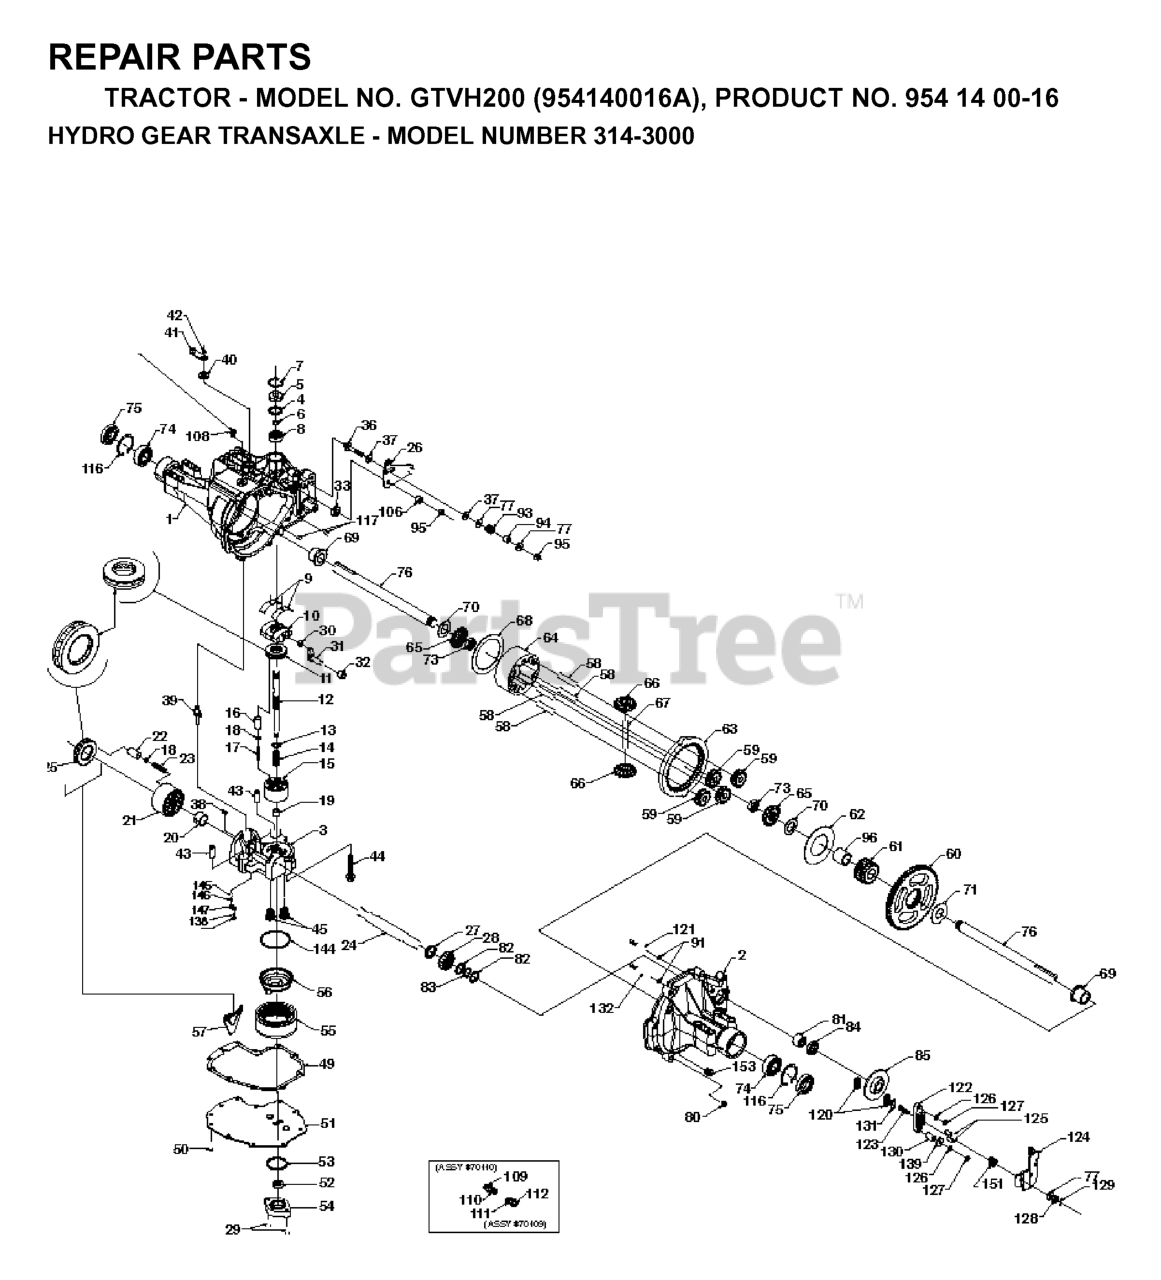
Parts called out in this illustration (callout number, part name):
1	GRIP, CLUTCH
2	SPRING
3	CLUTCH CONTROL KIT HUS
4	HANDLE WITH GRIPS
5	HANDLE, CONTROL, REAR WHEEL
6	CLUTCH CABLE
7	GRIPS, PAIR, 1" ID, BLACK
8	BOLT KIT CLUTCH CONTROL
9	CABLE KIT, CLUTCH
10	PIN KIT, REAR WHEEL
11	CONTROL ROD KIT HV
12	FASTENER KIT, HANDLE
13	THROTTLE CABLE KIT
14	THROTTLE CABLE
540007405	CLUTCH THROTTLE CONTROL HV
